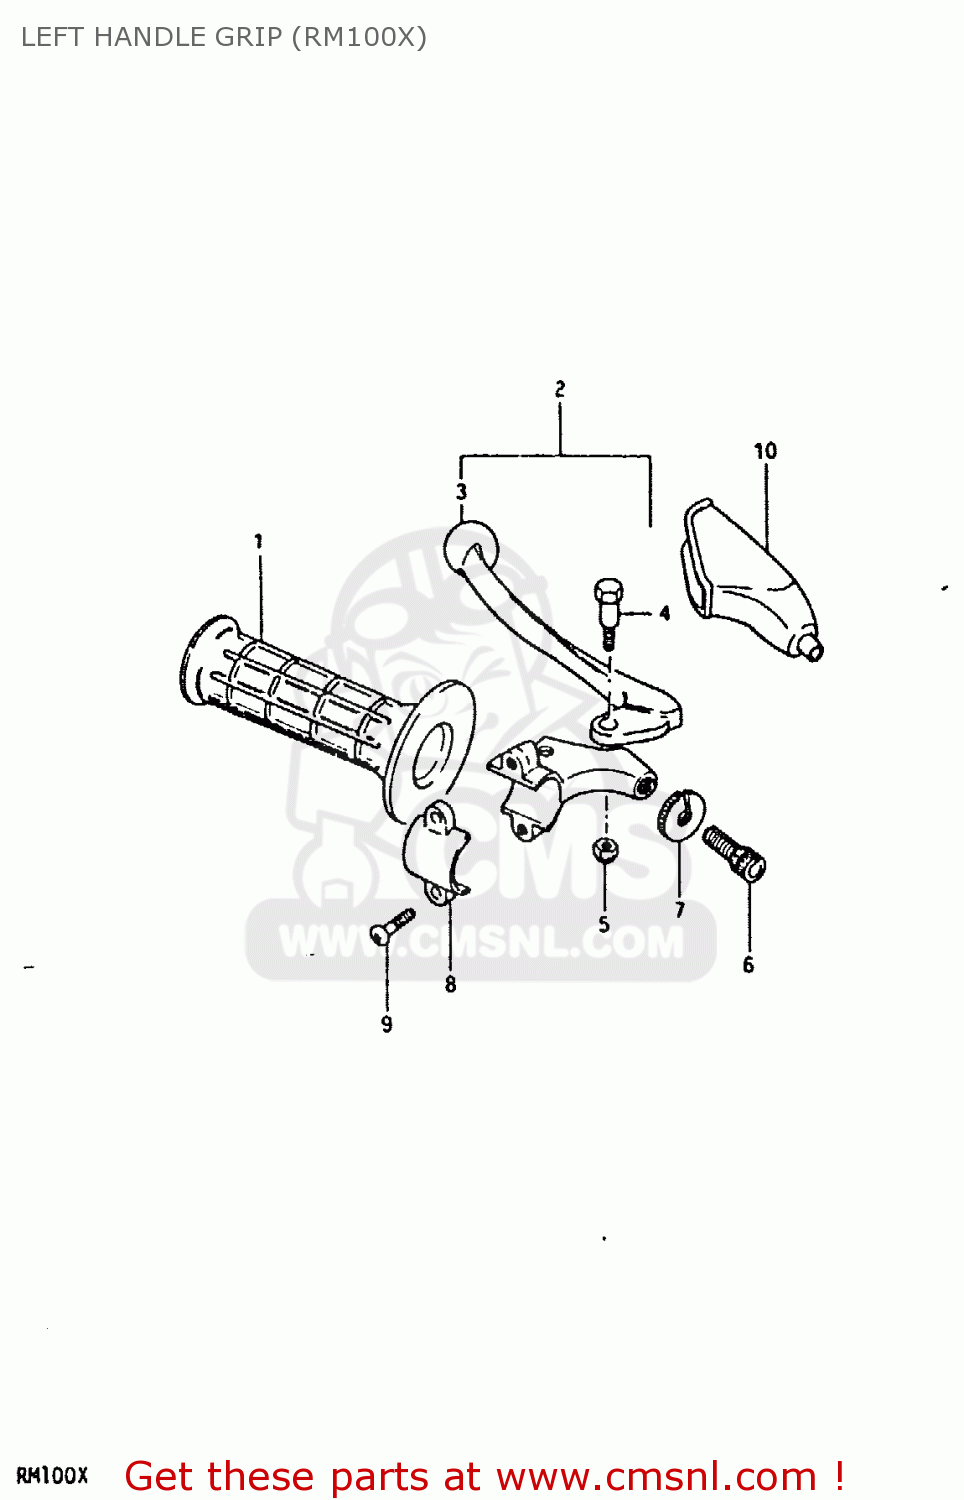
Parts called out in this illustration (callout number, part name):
1	GRIP,LEFT
2	LEVER ASSEMBLY
3	LEVER,CLUTCH
4	BOLT,LEVER
5	NUT 6MM
6	ADJUSTER,CABLE
7	NUT,CABLE ADJUSTER
8	BRACKET,LEVER
9	SCREW
10	COVER,CLUTCH LEVER
